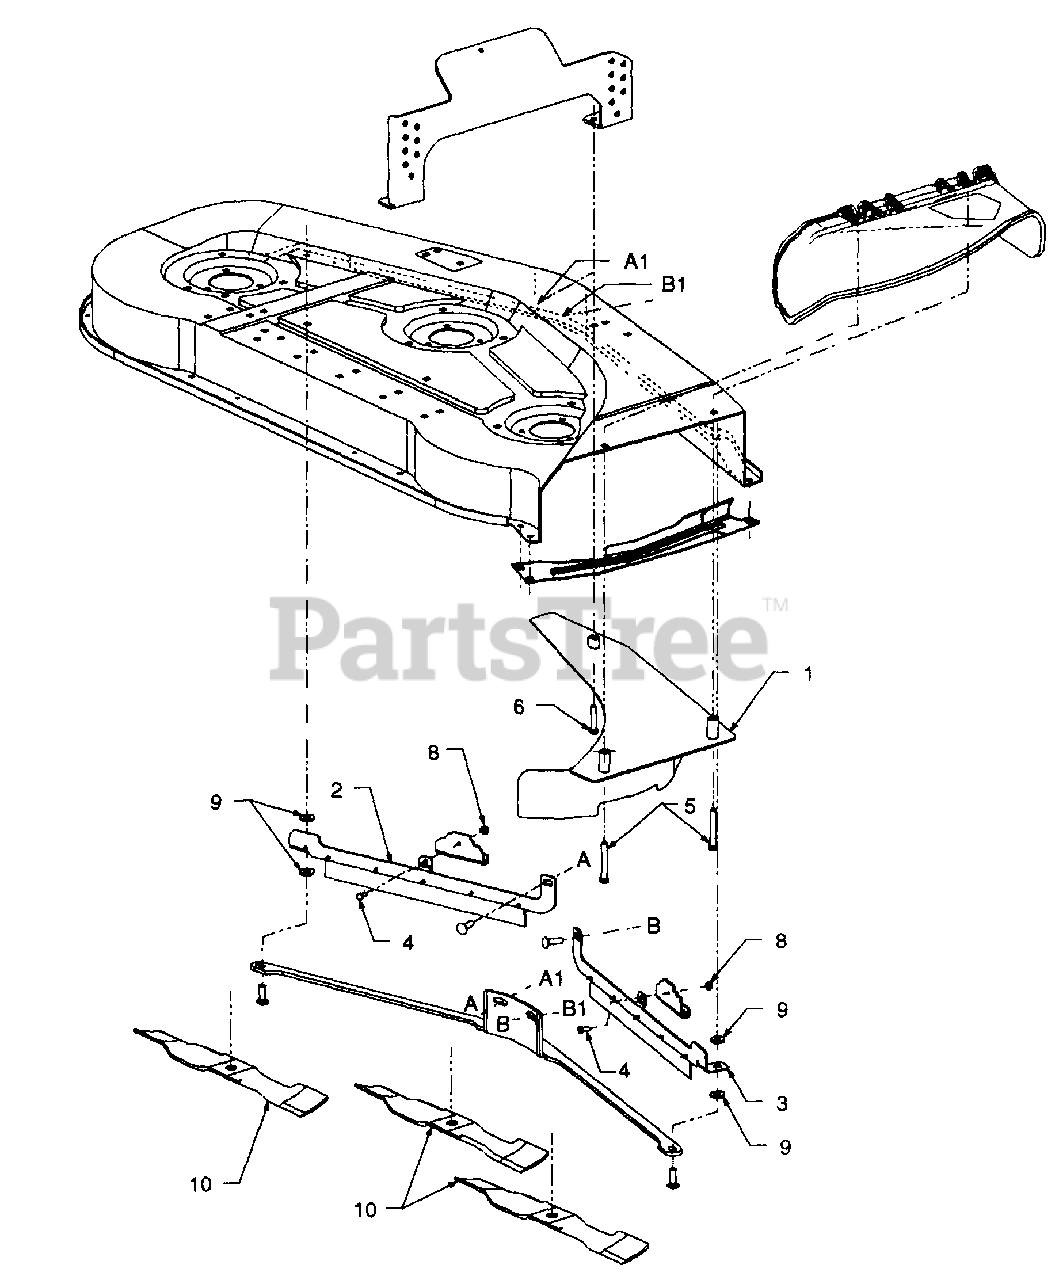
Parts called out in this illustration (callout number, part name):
4	Screw, Hex Cap, 1/4-20 X .62 GR5
5	Screw, Hex Cap, 3/8-16 X 2-1/4 GR5
6	Screw, Hex Cap, 3/8-16 X 1-3/4 GR5
8	Nut, Hex Flange Lock, 1/4-20
9	Washer, Flat, 406 X 1.0 X 105
10	Blade, Mulching, 16 5 Lg
